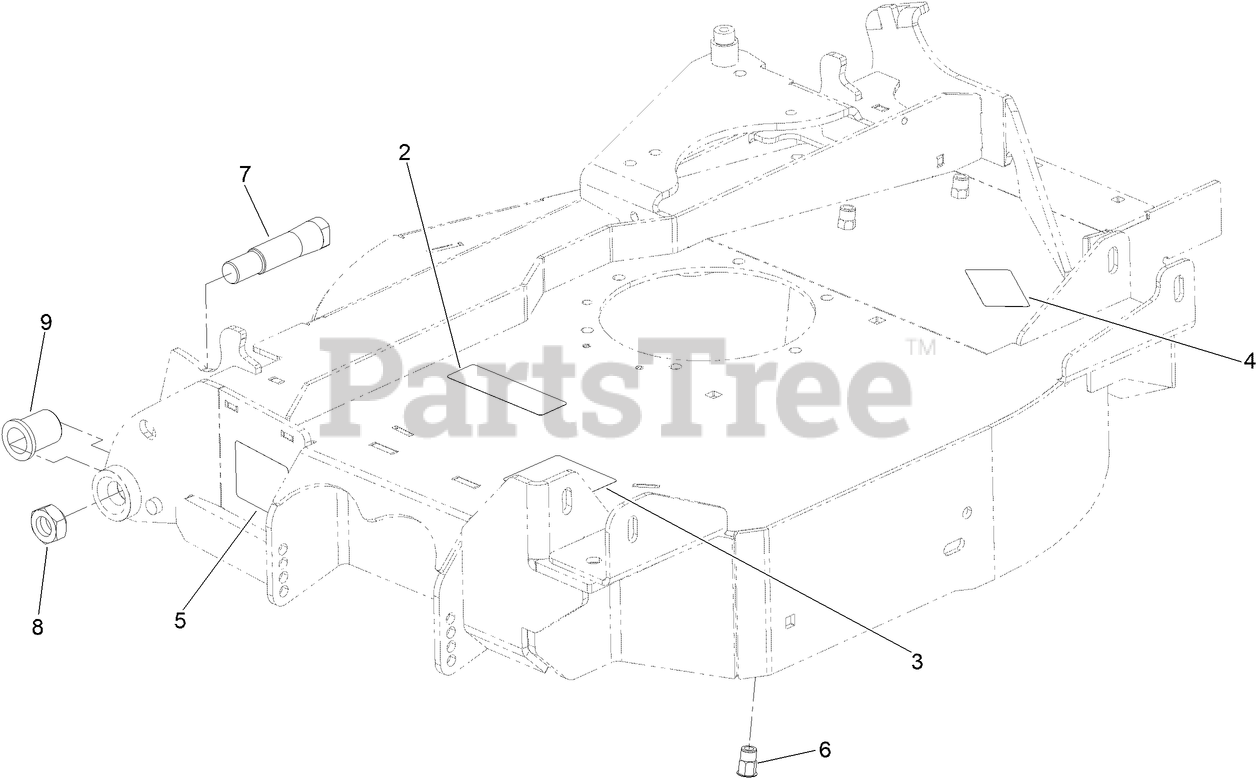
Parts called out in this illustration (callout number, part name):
2	DECAL-COVER, MISSING
3	DECAL-DANGER, THROWN OBJECT
4	DECAL-BOLT TORQUE
5	DECAL-WARNING, PINCH POINT
6	NUT-CLINCH,HEX
7	BOLT-PIVOT PIN
8	NUT-LUG
9	BUSHING-FLANGED
